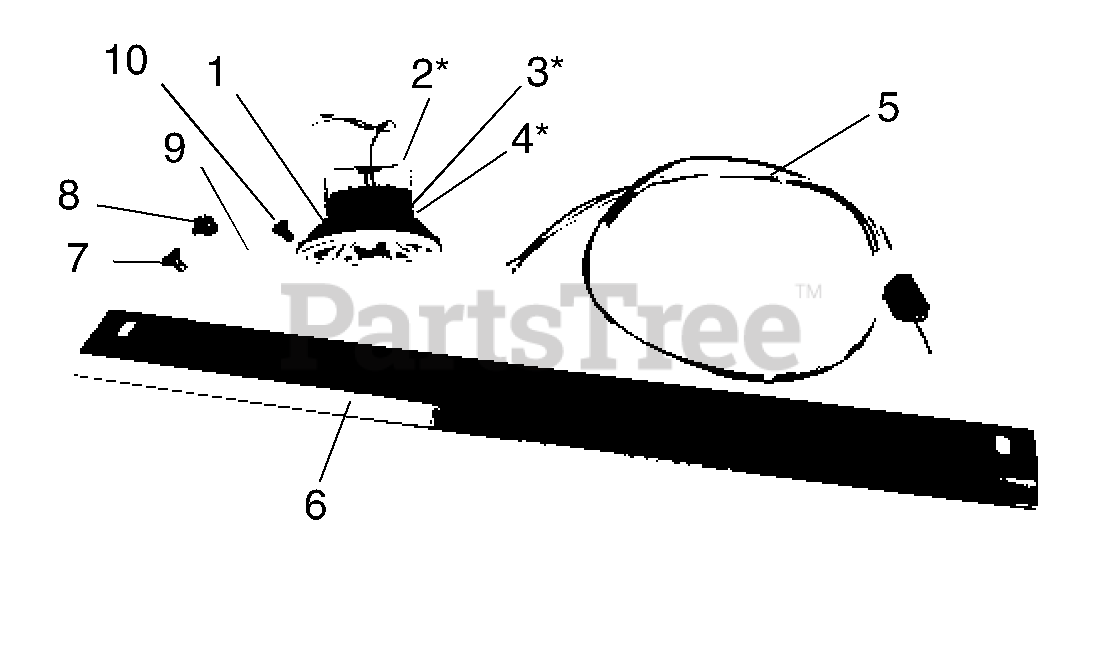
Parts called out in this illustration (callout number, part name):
1	KIT-ZOOM LITE
2	WMT, LIGHT BRACKET
3	WSHR-LK 4MMX1MM REG CL ZINC
4	SCREW-M4X.07X8 SHCS CLZNC
5	HARNESS, LIGHT
6	BKT-HARNESS
7	BLT-RDHDSQNK .31-18X.75 G5BZ
8	NUT-LK-TOP-FLG .31-18 BLKZC
9	@WSHR-LK .31X.078 REG YWZC
10	SCR-CAP BTHD.31-18X.50 GR5 YZ
